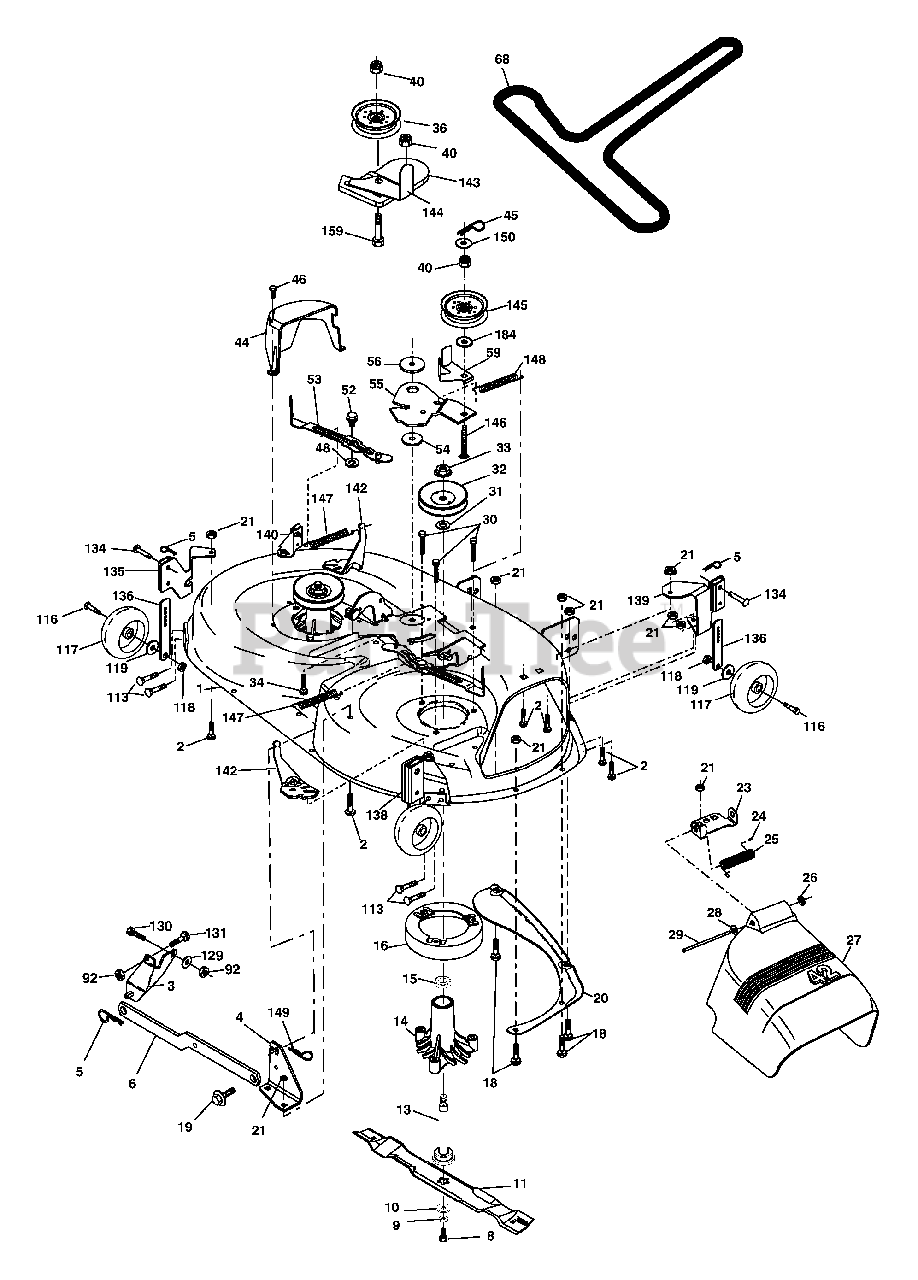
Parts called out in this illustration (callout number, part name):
1	Mower Deck Assembly, 42"
2	Bolt
3	Bracket Asm Fr. Sway Bar 3/42
4	Bracket Asm Deck 42" Sway Bar
5	Retainer Spring
6	Bar Sway Deck
8	Bolt 3/8-24 x 1.25 Gr. 8 patched
9	Washer, Lock
10	Washer, Hardened
11	Blade, Mulching 42" Std
11	Blade Mulching 42" Premium
11	Blade Mower 42" Hi-Lift
13	Shaft Assembly, Mandrel, Vented
14	Housing, Mandrel, Vented
15	Bearing, Ball, Mandrel
16	Stripper, Mandrel Deck
18	Bolt, Carriage 5/16-18 x 5/8
19	Bolt, Shoulder
20	Baffle, Vortex
21	Nut
23	Bracket, Deflector Mower 42"
24	Cap, Sleeve 80 x 112 Blk Mower
25	Spring, Torsion, Deflector 2 52
26	Nut, Push Phos & Oil
27	Shield, Deflector 42" Blk
28	Washer 11/32 x 5/8 x 16 Ga.
29	Rod, Hinge 42" 6 75 W/G
30	Screw Thdrol
31	Washer, Spacer Mower Vented
32	Pulley, Mandrel
33	Nut, Toplock
34	Bolt Carr SH 3/8-16 x 1-1/2 Gr.5
36	Pulley, Idler, Flat
40	Nut Lock 3/8-16
44	Guard, Mandrel, LH
45	Retainer
48	Washer, Hardened
52	Bolt, Shoulder 5/16-18 unc
53	Arm Assembly, Pad, Brake
54	Washer, Hardened
55	Arm, Idler
56	Spacer, Retainer
59	Guard TUV Idler
67	Knob Round
68	V-Belt, 42" Mower
92	Nut Lock Hex W/Ins 3/8-16 UNC
113	Screw 5/16-18
116	Bolt, Shoulder
117	Wheel, Gauge
118	Nut Centerlock 3/8-16
119	Washer 3/8 x 7/8 x 14 Ga.
129	Washer 13/32 x 13/16 x 12 Ga.
130	Bolt Fin Hex 3/8-16 UNC x 1 Gr. 5
131	Bolt RDHD SQNK 3/8-16 UNC x 1
134	Pin Head Rivet
135	Bracket Asm. Whl Ga. R LH
136	Bar Adjusting Gauge Wheel
138	Bracket Asm Whl Ga. R RH
139	Bracket Asm. Whl Ga. F RH
140	Bracket Asm Whl Ga. F LH
142	Arm Spring Brake Mower
143	Bracket Arm Idler 42"
144	Keeper Belt 42" Clutch Cable
145	Pulley Idler Flat
146	Bolt Carriage Idler
147	Spring Extension
148	Spring Return Idler
149	Retainer Spring Yellow
150	Washer 9/32 x 3/4 x 10 Ga.
159	Bolt Rdhd Sqn 3/8-16 unc x 1-3/4
184	Washer 13/32 x 7/8 x 10 Ga.
